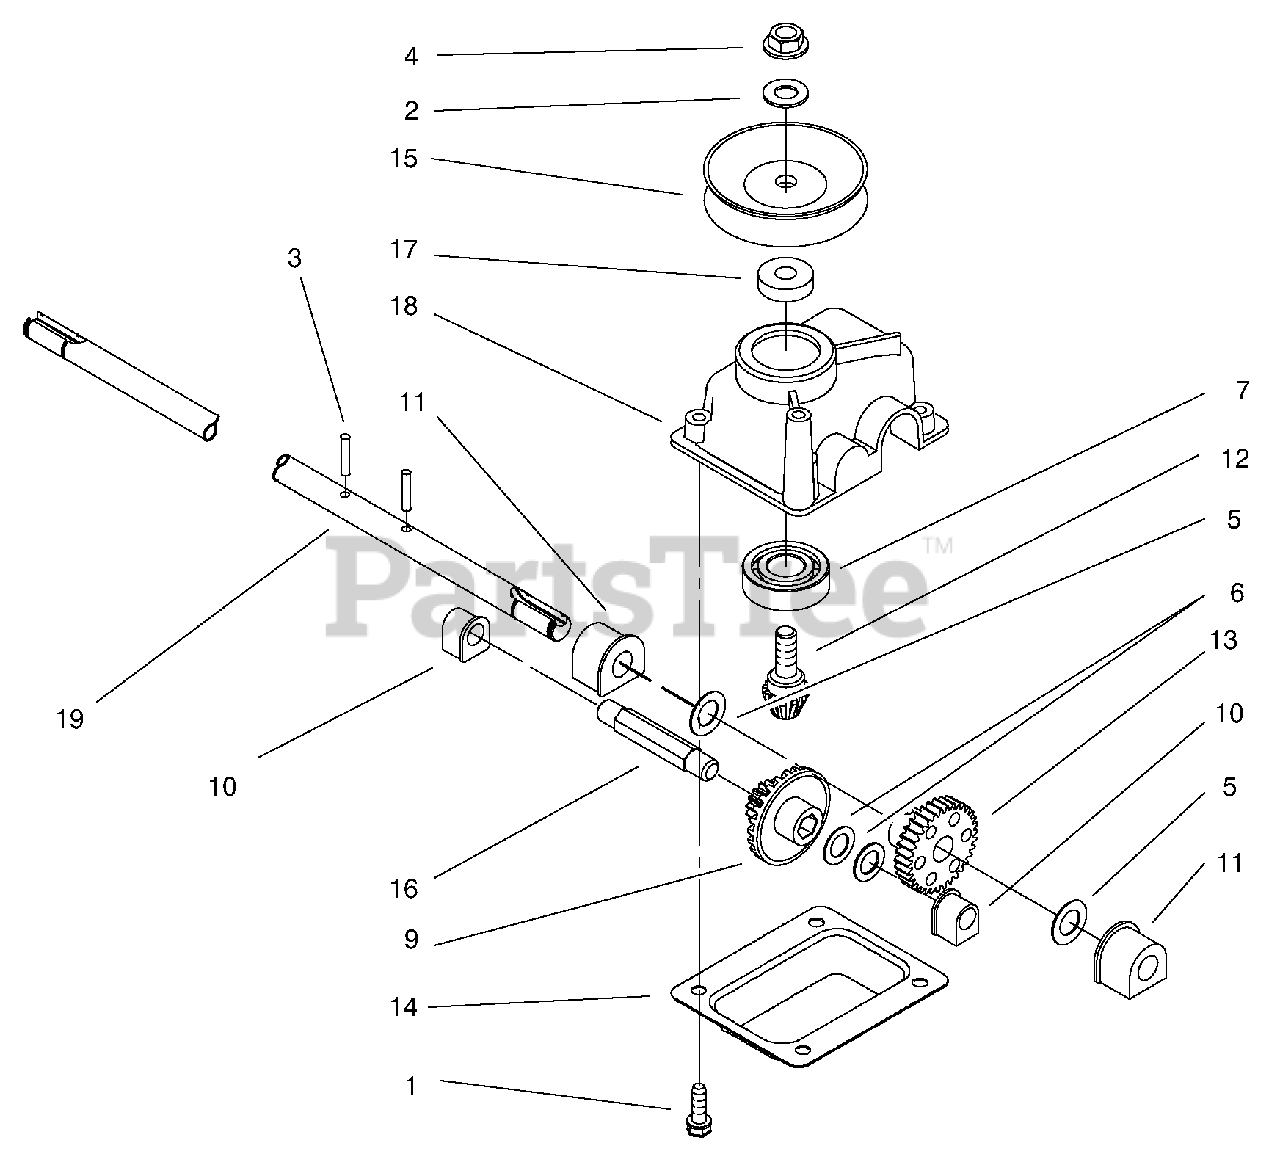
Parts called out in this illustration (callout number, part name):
1	Screw-HH
2	Washer-Flat
3	Pin-Groove
4	Nut-Lock, NI
6	Washer-Thrust
7	Bearing-Ball
9	Gear-Bevel
11	Bushing-Output
12	Gear-Bevel, Pinion
14	Cover-Gear Case
15	Half-Pulley
16	Shaft-Intermediate
18	Gearcase
19	Shaft-Output
